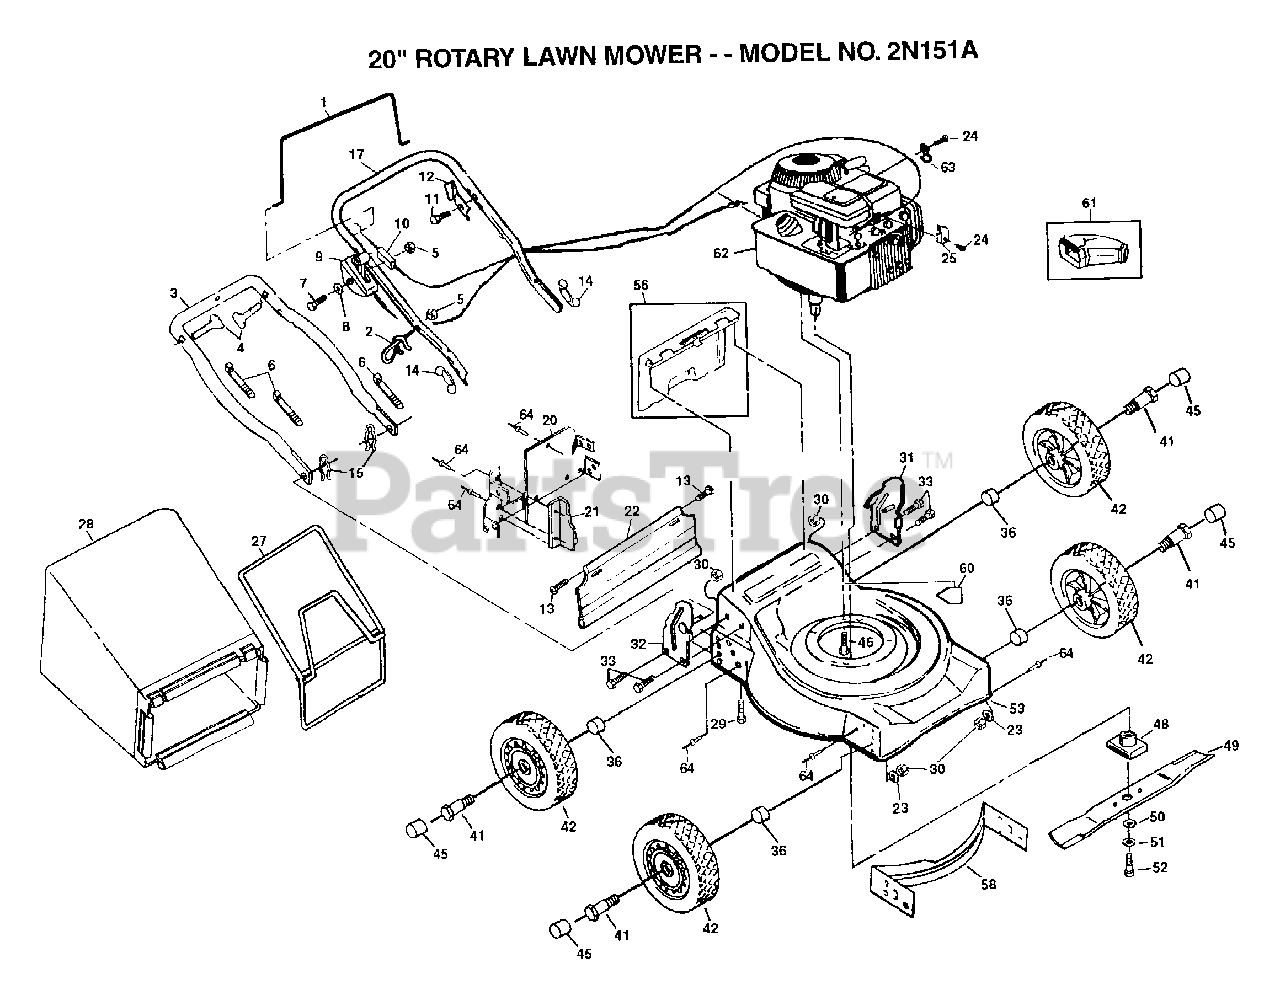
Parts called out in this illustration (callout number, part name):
1	CONTROL BAR PM
2	ROPE GUIDE
4	BOLT.HANDLE.LM
8	WASHER PM
9	CONTROL THROTTLE
10	"CABLE,ENG ZONE CO"
11	TAPPING SCREW
12	"BRKT,UPSTOP"
13	HINGE SCREW
14	"NUT,WING PM"
15	HAIRPIN COTTER
20	PLATE.BACK.20RD
23	WASHER PM
24	SCREW PM
25	CABLE CLAMP
27	FRAME.CATCHER.ASM
28	GRASS BAG
29	SCREW
30	LOCKNUT PM
33	SCREW
41	AXLE BOLT
42	WHEEL.ASM
45	HUB CAP-PLASTIC
46	SCREW
48	BLADE ADAPTOR
49	BLADE.STAND.20INC
50	"WASHER,HARDEN"
51	LOCKWASHER
52	SCREW
53	KIT.HSG.20RD
56	"KIT, REAR DOOR PM"
60	DECAL HYT
63	GUIDE CLIP PM
64	BLIND RIVET
